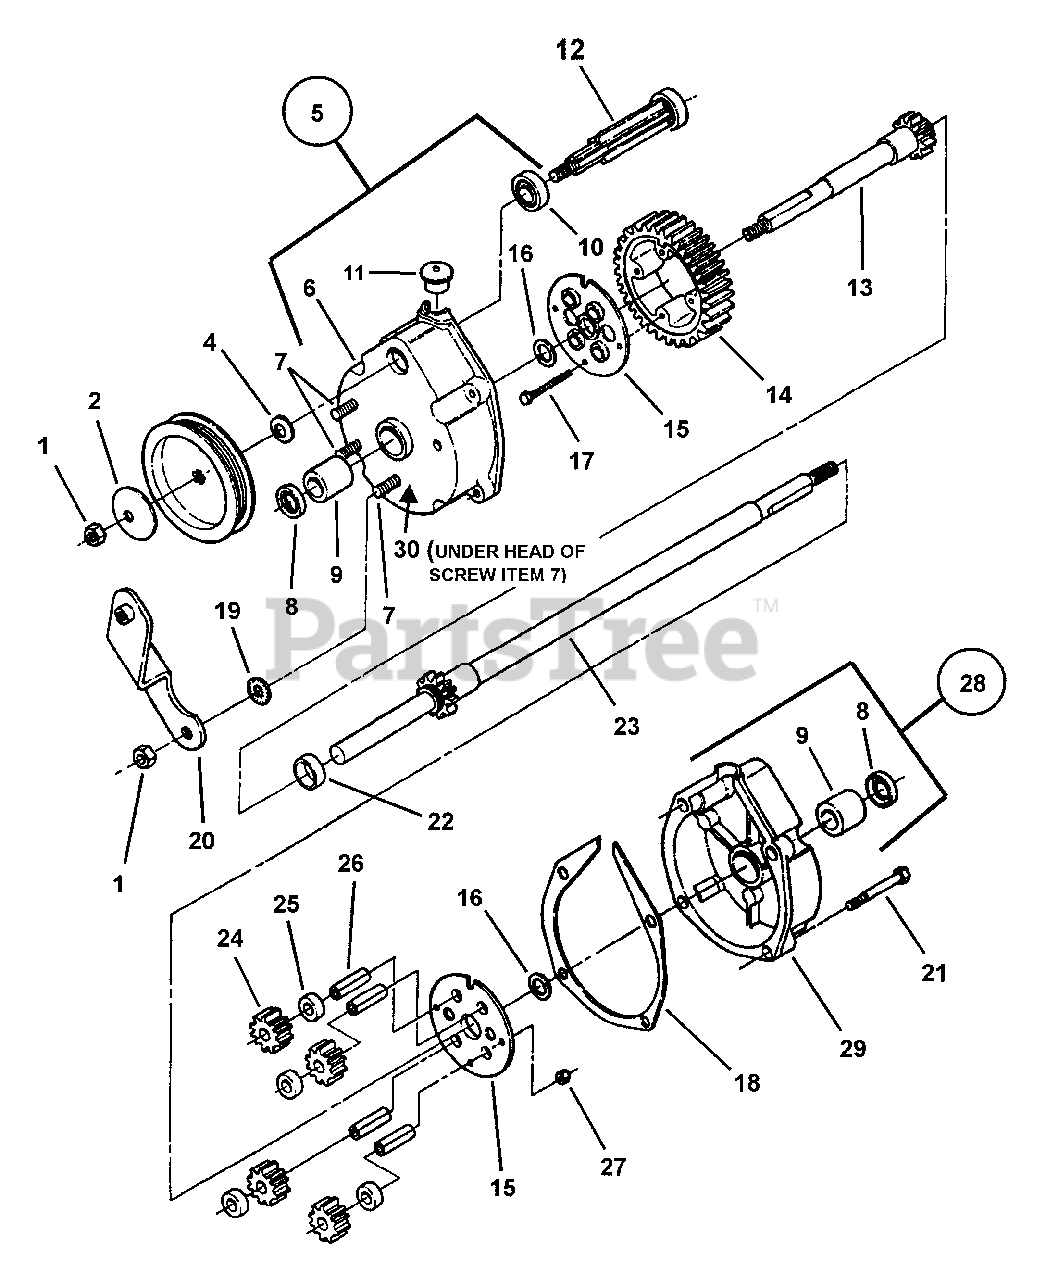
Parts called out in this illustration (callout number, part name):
1	NUT, 5/16-24 Hex Lock
2	WASHER, Spring
3	PULLEY, Poly-Vee Belt
4	WASHER, Spring
5	ASSEMBLY, Housing Right
6	HOUSING, Right Side
7	SCREW, 5/16-24 x 1-1/8" Rib Neck, Grade 5
8	SEAL, 5/8 I.D.
9	BEARING, Differential
10	BEARING, Ball
11	PLUG, Housing
12	GEAR, Input
13	AXLE, Short
14	GEAR, Differential (46 Tooth)
15	PLATE
16	WASHER, Thrust
17	SCREW, #10-32 x 1-1/2" Hex Head Cap, Grade 5
18	GASKET, Housing
19	WASHER, 5/16 Internal/External Tooth Lock
20	BRACKET, Differential
21	SCREW, 1/4-20 x 1-1/4" Self-Tapping
22	SPACER, Axle Gear
23	AXLE, Long
24	GEAR, Pinion (12 Tooth)
25	SPACER, Pinion Gear
26	SHAFT, Pinion
27	NUT, #10-32 Hex Nyloc
28	ASSEMBLY, Housing Left
29	HOUSING, Left Side
30	GASKET, 5/8 O.D.
